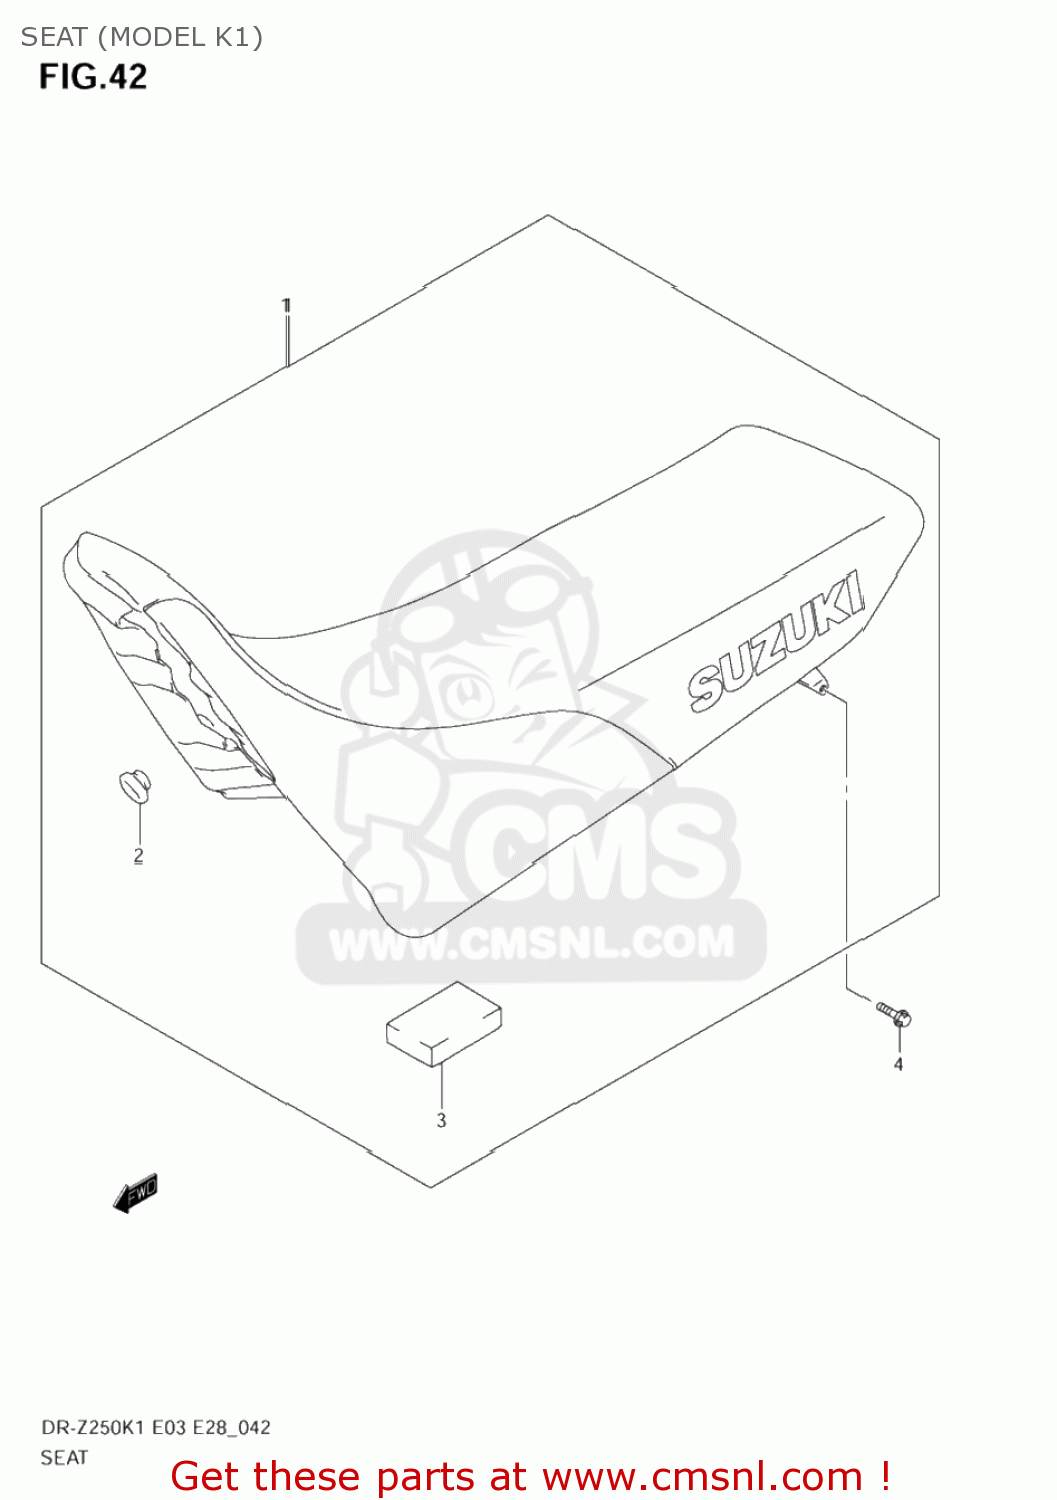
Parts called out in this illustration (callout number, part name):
1	SEAT ASSY
2	CUSHION
3	CUSHION
4	BOLT
